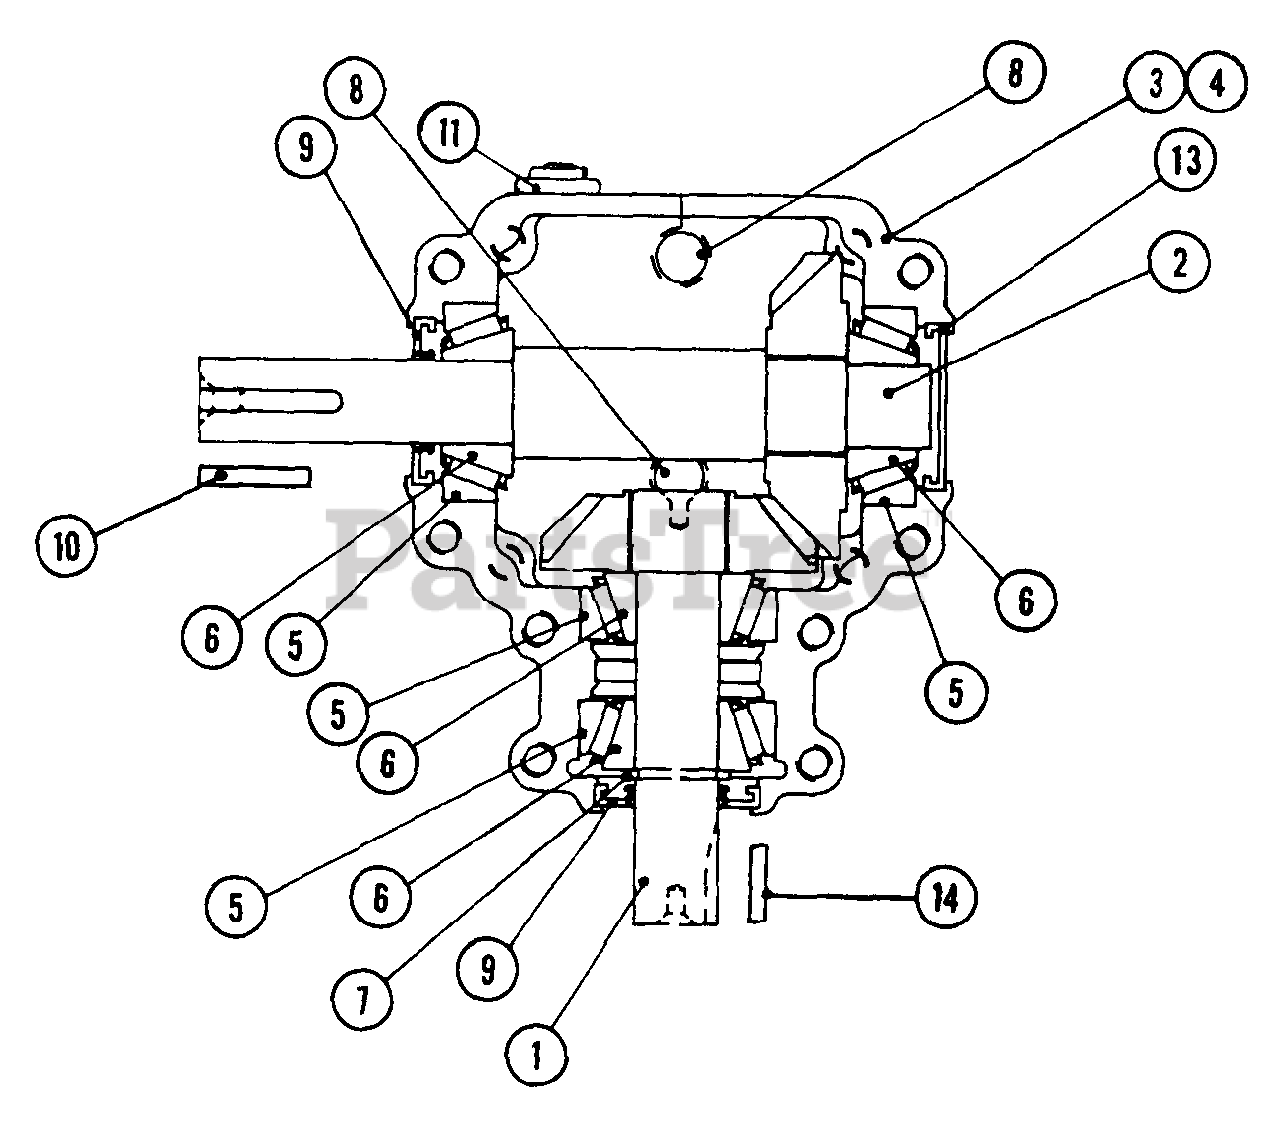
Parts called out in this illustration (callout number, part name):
1	SHAFT - pinion with gear
2	SHAFT - cross with gear
3	HOUSING - with tapped holes
5	CUP - bearing
6	CONE - bearing
7	RING - retaining
8	PLUG - pipe 1/4"
10	KEY 3/16" x 1" input shaft
11	PIPE - vent
13	CAP - end
14	KEY - 3/16" x 5/8" output shaft
